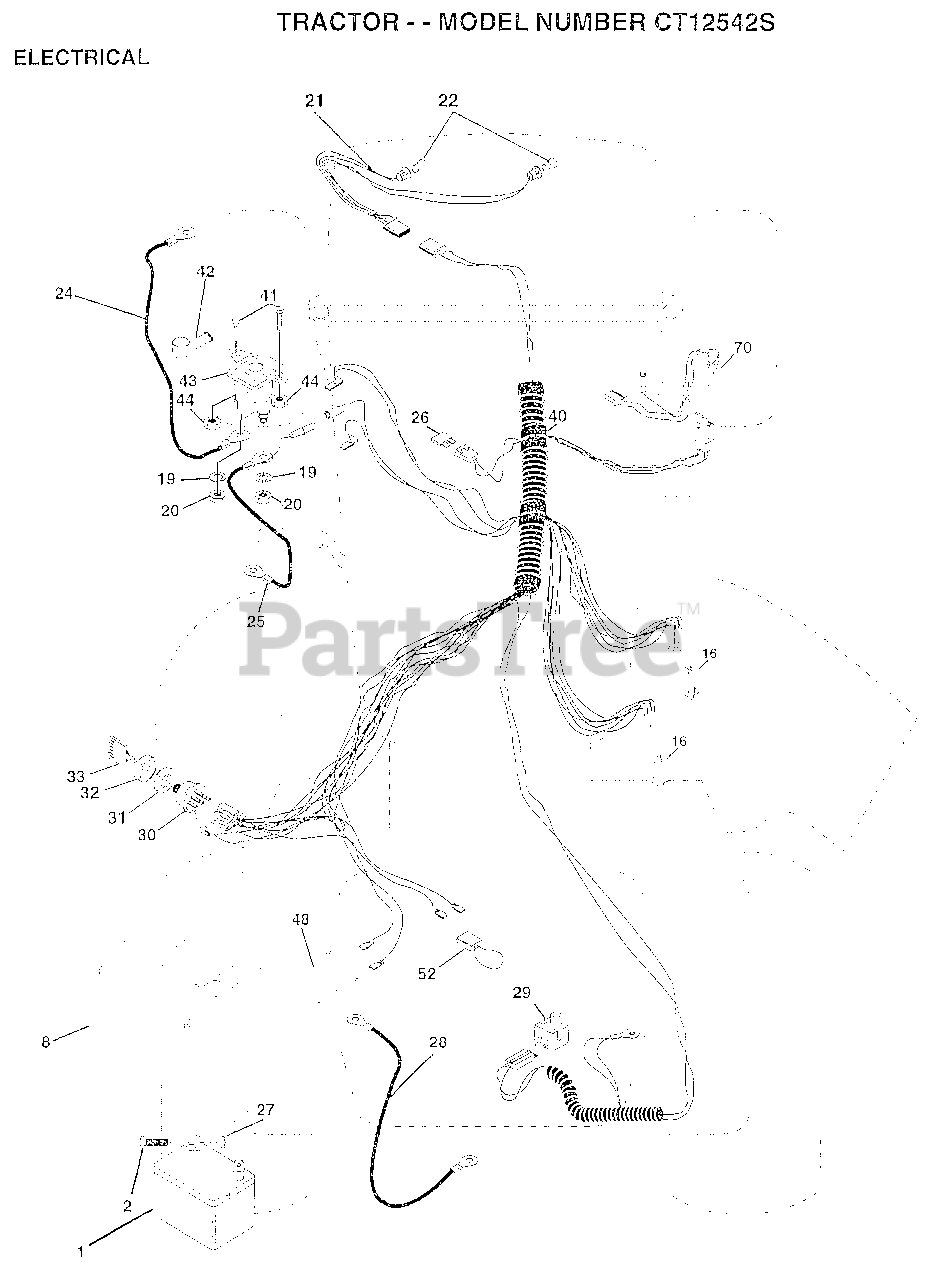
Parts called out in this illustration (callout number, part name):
2	BOLT LT
8	"CASE,BATTERY.MECH"
16	SWITCH INTERLOCK
20	NUT
21	HARNESS.ASM.LIGHT W/4152J
22	HEADLAMP BULB
24	"CABLE T, BATTERY"
25	CABLE.BTRY.6GA.RD
26	FUSE.15 AMP
27	NUT
28	CABLE T
29	SWITCH SEAT
30	SWITCH IGN 4POS
31	NUT IGNITION
32	COVER KEY SWITCH
33	KEY
40	HARNESS.IGNITION
41	BOLT HXHD FIN
44	NUT HXKEP 1/4X20
48	ADAPTER AMMETER
52	PROTECTION LOOP
70	HARNESS.ENGINE
